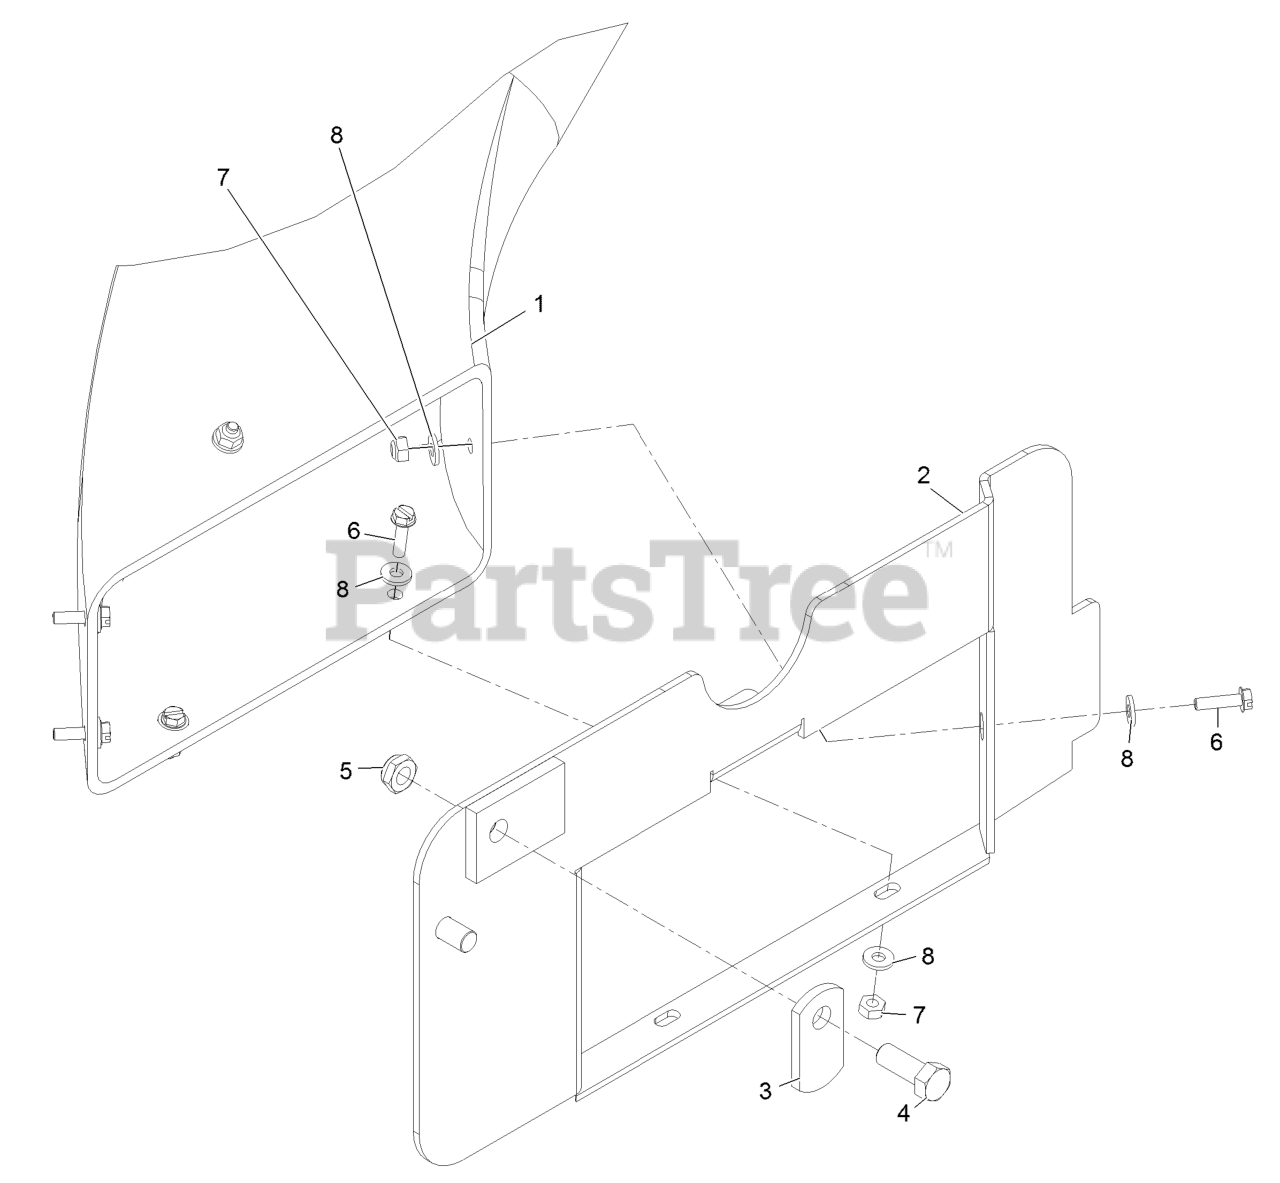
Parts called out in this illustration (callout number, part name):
1	BOOT,LOWER
2	BOOT FRAME ASM
3	LATCH-CATCHER, GRASS
4	SCREW-HH
6	SCREW-HWH
7	NUT-LOCK, NI
8	WASHER-FLAT
